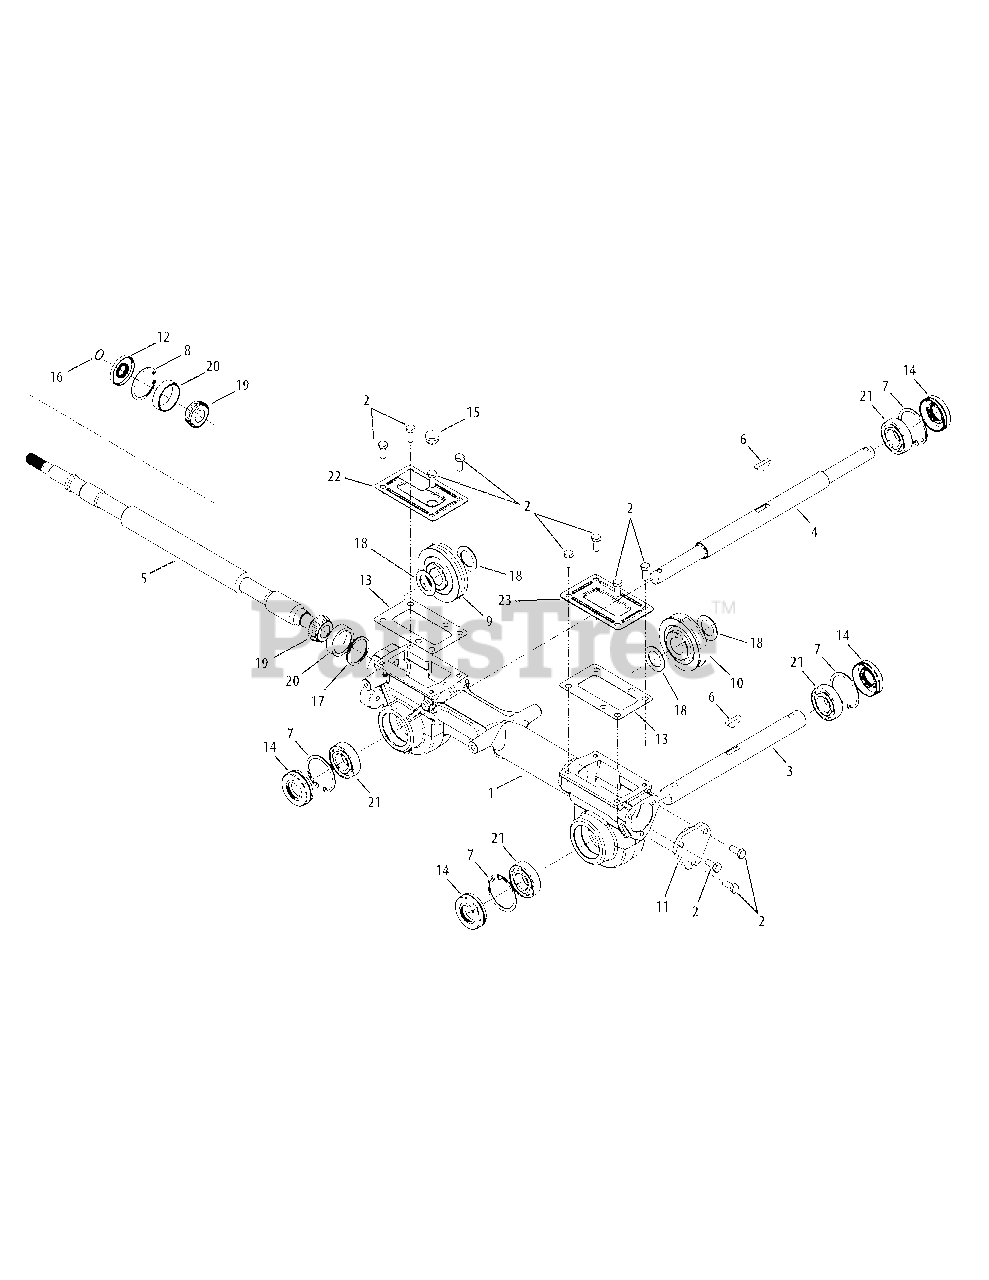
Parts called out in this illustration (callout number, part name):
1	Housing, Transmission
2	Hex Screw, 5/16-18, .75, Gr5
3	Shaft, Tiller
4	Shaft, Wheel
5	Shaft, Worm
6	Key, Hi Pro .25 x 1.062
7	Retaining Ring
8	Retaining Ring, Int
9	Worm Gear, 61t, RH
10	Worm Gear, 30t, LH
11	Bearing Cover
12	Seal, Oil, .750 Shaft x 1.783 Bore
13	Gasket, Gear Housing
14	Seal, Oil, 1.00 Shaft x 2.00 Bore
15	Rubber Plug, Oil
16	Wire Ring
17	Washer, Flat, 1.50 x 1.75 x .062
17	Washer, Flat, 1.50 x 1.75 x .005
17	Washer, Flat, 1.50 x 1.75 x .03
17	Washer, Flat, 1.50 x 1.75 x .010
18	Washer, Flat, 1.010 x 1.56 x .060
19	Cone Bearing
20	Bearing Cup
21	Ball Bearing
22	Cover, Transmission
23	Cover, Transmission
